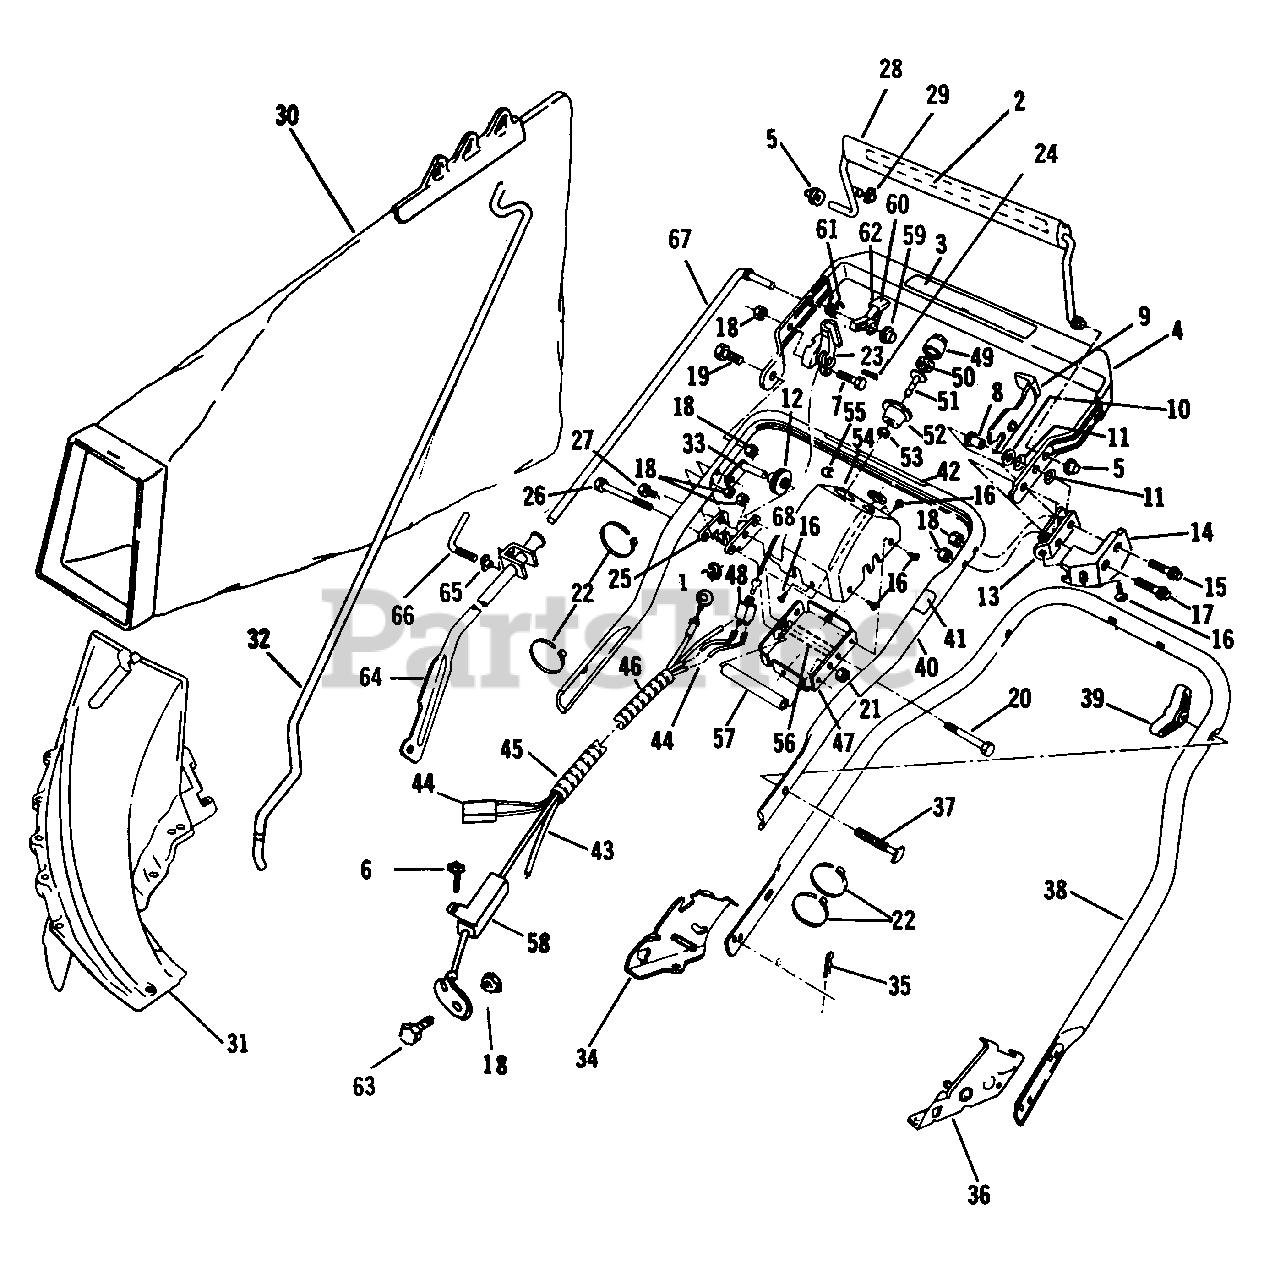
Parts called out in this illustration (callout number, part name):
1	Ring-Retainer
2	Decal-Blade Control
3	Decal-Drive Control
4	Top Handle and Grip Assembly
5	Pushnut
6	Screw-Cable to Eng. Mtg. Plt.
7	Bolt-Hex
8	Spacer-Flanged
9	Lever-Lockout
10	Washer-Plain
11	Washer-Spring
12	Pulley
13	Down-Stop
14	Guard-Lockout
15	Bolt-Shoulder
16	Screw
17	Bolt-Shoulder-L.H.
18	Locknut
19	Bolt-Shoulder-R.H.
20	Screw-Hex Hd. Cap
21	Nut-Hex Jam
22	Tie Strap
23	Cam and Roll Pin Assembly
24	Roll Pin
25	Bracket-Clutch Cable
26	Screw
27	Screw-Clutch Cable Brk't.
28	Control Lever and Nut Assembly
29	Nut-Acorn
30	Bag Assembly
31	Chute Assembly
32	Rod-Grass Bag
33	Pivot-Bracket Pulley
34	Bracket-Handle-R H
35	Hair Pin
36	Bracket-Handle-L.H.
37	Screw
38	Handle Section-Bottom
39	Knob
40	Handle Section-Center
41	Decal-Drive Lockout
42	Decal-Starting Inst.
43	Tubing-Primer
44	Wire Harness Assembly
45	Spiral Tubing
46	Spiral Tubing
47	Plate-Cover Assembly
48	Switch Assembly
49	Primer Bulb
50	Filter
51	Primer Base
52	Cup
53	Locknut
54	Cover
55	Decal
56	Spacer
57	Spacer
58	Control Cable Assembly
59	Pushnut
60	Decal-Stop-Latch Lever
61	Spring-Torsion
62	Stop-Latch Lever
63	Bolt-Shoulder-Cable to Arm
64	Control Lever Assembly
65	Nut-Control Lever Clamp
66	Lever-Rod Clamp
67	Rod-Control
68	Key-Switch (2)
